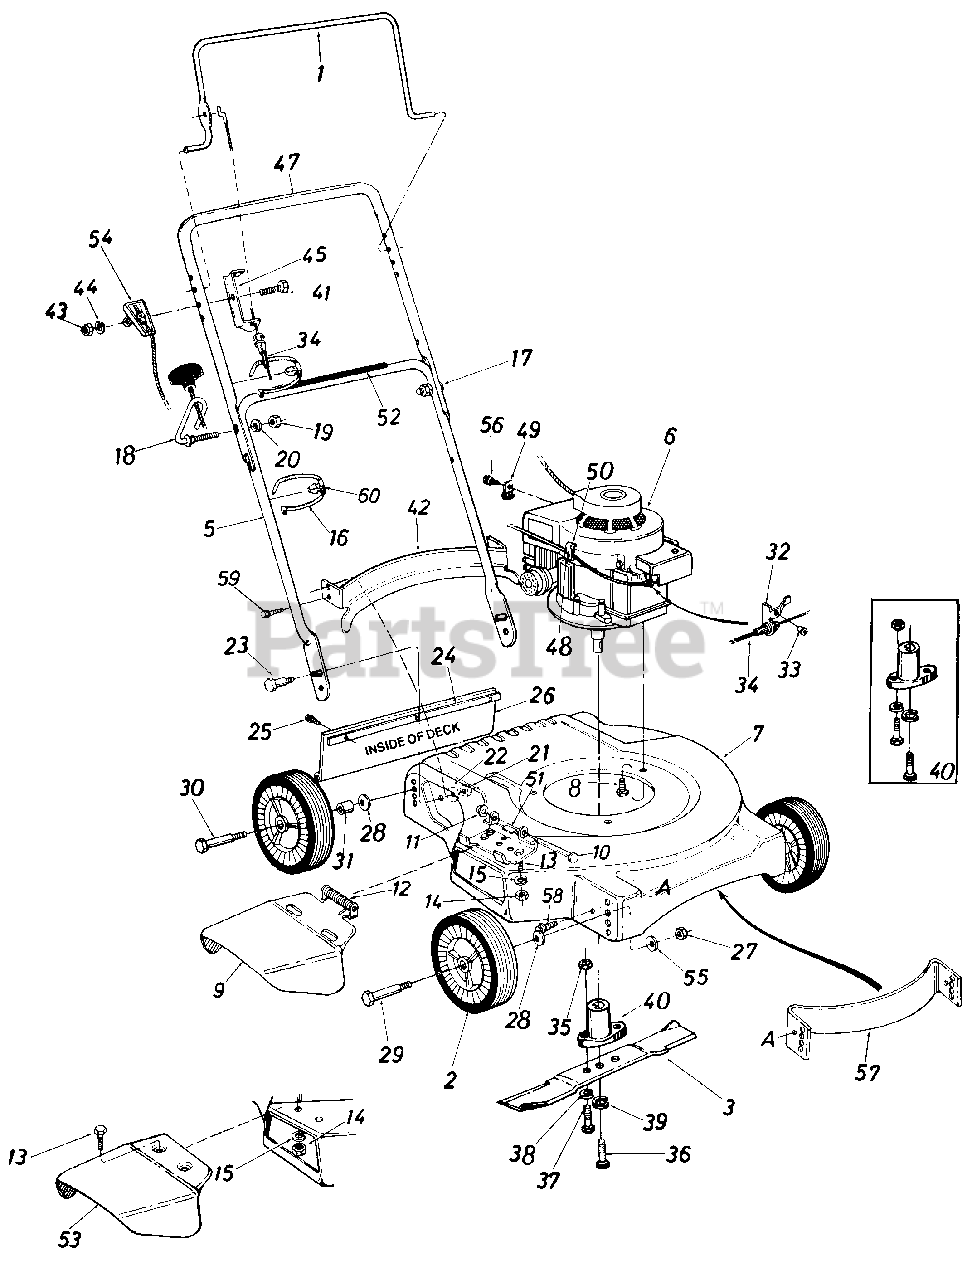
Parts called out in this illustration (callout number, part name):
1	Control Handle
2	Plastic Wheel Ass'y.
3	20" Blade
5	Lower Handle (Chrome)
6	Engine
8	Hex Wash. Hd TT-Tap Scr. 3/8-16 x 1.00" Lg.
9	Chute Deflector Ass'y.
10	Pivot Pin
11	Cap Speed Nut 1/4" Rod
12	Torsion Spring
13	Hex Bolt 1/4-20 x .50" Lg.
14	Hex Nut 1/4-20 Thd.*
15	L-Wash. 1/4" I.D.
16	Cable Tie
17	Curved Carriage Bolt 5/16-18 x 1.38" Lg.
18	Rope Guide Bolt
19	Hex Nut 5/16-18 Thd.
20	L-Wash. 5/16" I.D.
21	Hex Ins. L-Nut 5/16-18 Thd.
22	Bell-Wash. .345" I.D. x .88" O.D.
23	Shld. Bolt .437" Dia. x .180" Lg.
24	Retainer Strip
25	Hex Wash. Hd. Self-Tap Scr. 1/4" x .62" Lg.
26	Rear Flap Ass'y.
27	Hex Nut 3/8-16 Thd.
28	Bell-Wash. .400" I.D. x .88" O.D.
29	Shld. Bolt
30	Shld. Bolt
31	Spacer
32	Cable Bracket
33	Pop Rivet .156" Dia. x 379
34	Control Cable-43.0" Lg.
35	Hex Nut 5/16-24 Thd.*
36	Hex Bolt 3/8-24 x 1.00" Lg. (Grade 5)
37	Hex Bolt 5/16-24 x 1.00" Lg. (Grade 5)
38	L-Wash. 5/16" I.D.*
39	L-Wash. 3/8" I.D. Heavy Duty
40	Blade Adapter Kit
41	Hex Bolt 1/4-28 x 1.75 Lg.*
42	Rear Bafflet
43	Hex Nut 1/4-28 Thd.
44	L-Wash. 1/4" I.D.
45	Cable Mounting Brkt.
47	Upper Handle (Chrome)
48	Hex B-Tap Scr. #10 x .38" Lg.
49	Casing Clamp
50	Casing Clamp
51	Hinge Plate
52	Instruction Label-Handle
53	Chute Deflector
54	Throttle Control Ass'y. Comp.
55	Bell-Wash. .39" I.D. x 1.13" O.D.
56	Hex AB-Tap Scr. #8 x .38" Lg.
57	Bafflet
58	Hex B-Tap Screw 1/4 x 38"
59	Hex Tap Screw #10 x .50" Lg.
60	Cable Anchor
